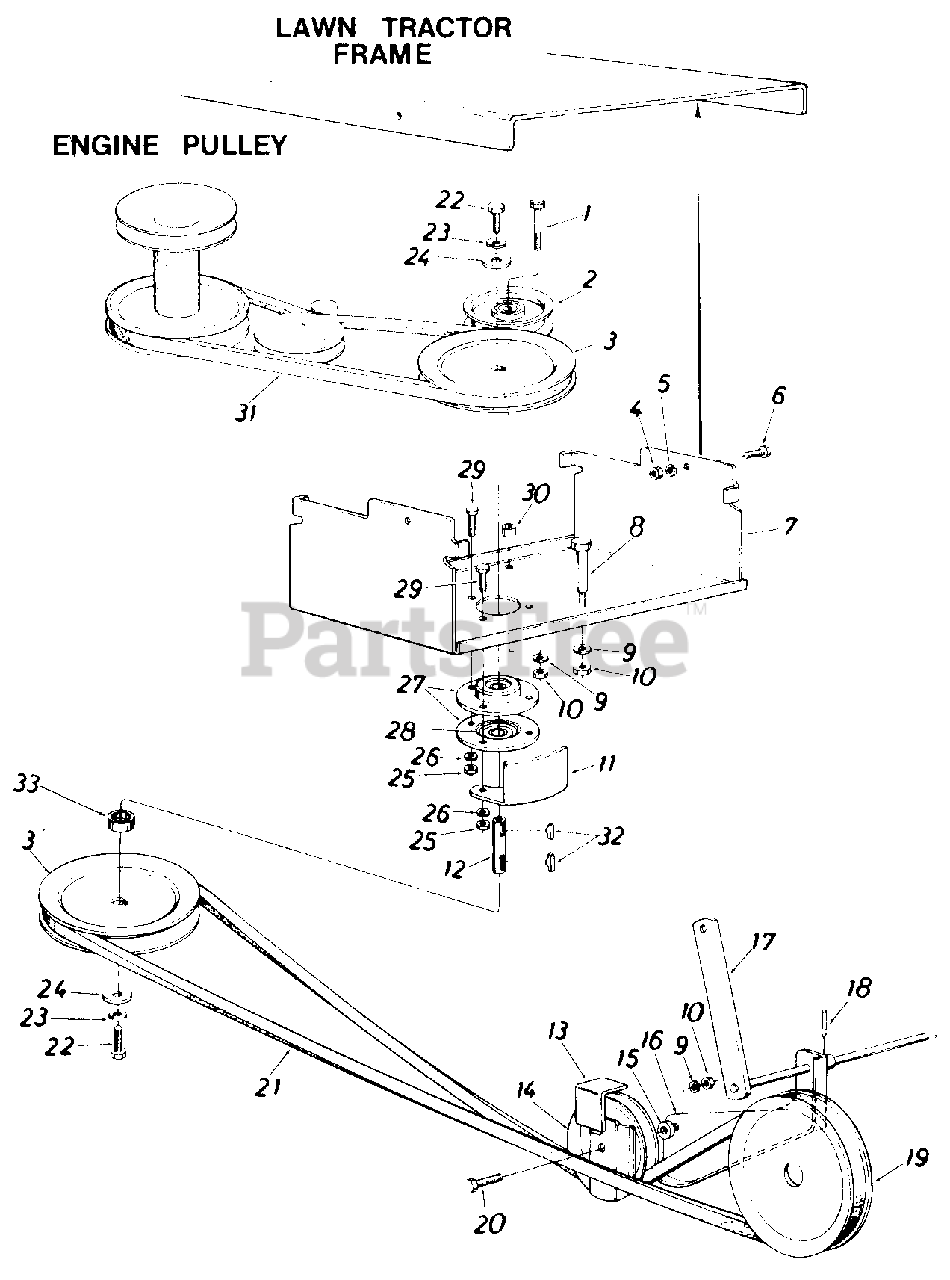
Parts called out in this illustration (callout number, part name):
1	Hex Bolt 3/8-16 x 2.00" Lg.*
2	Fl.-Idler w/Flanges 3-3/4" O.D.
3	5/8" "V"-Pulley .790" I.D. x .650" O.D.
4	Hex Nut 3/8-24 Thd.*
5	L.-Wash. 3/8" I.D. Heavy Duty
6	Hex Bolt 3/8-24 x .88" Lg.*
7	Carriage Bracket
8	Shoulder Bolt .498" Dia. x 1.64
9	L.-Wash. 3/8" I.D.*
10	Hex Nut 3/8-16 Thd.*
13	Belt Separator Plate
14	Fl.-Idler w/Flanges 3.25" O.D.
15	Fl.-Wash. .406" I.D. x 1.25" O.D. x .164
18	Spring Pin Roll 3/16" Dia. x 1.50" Lg.
19	5/8" V-Pulley 1.50" I.D. x 6.50" O.D.
20	Hex Bolt 3/8-16 x 1.75" Lg.*.
21	"V"-Belt 1/2" x 95.0" Lg.
22	Hex Bolt 5/16-18 x .88" Lg. Spec.
23	L.-Wash. 5/16" I.D.*
24	Fl.-Wash. .344" I.D. x 1.125" O.D. x .125
25	Hex Nut 5/16-18 Thd.*
26	L.-Wash. 5/16" I.D. *
27	Bearing Housing 1.85" I.D.
28	Ball Bearing .787" I.D. x 1.85" O.D.
29	Hex Sems Bolt 5/16-18 x .75"
30	Spacer
31	Belt 1/2" Wide x 52" Long
32	H i-Pro Key 3/16" x 5/8"
33	Spacer-.80" I.D. x 1.0" O.D.
